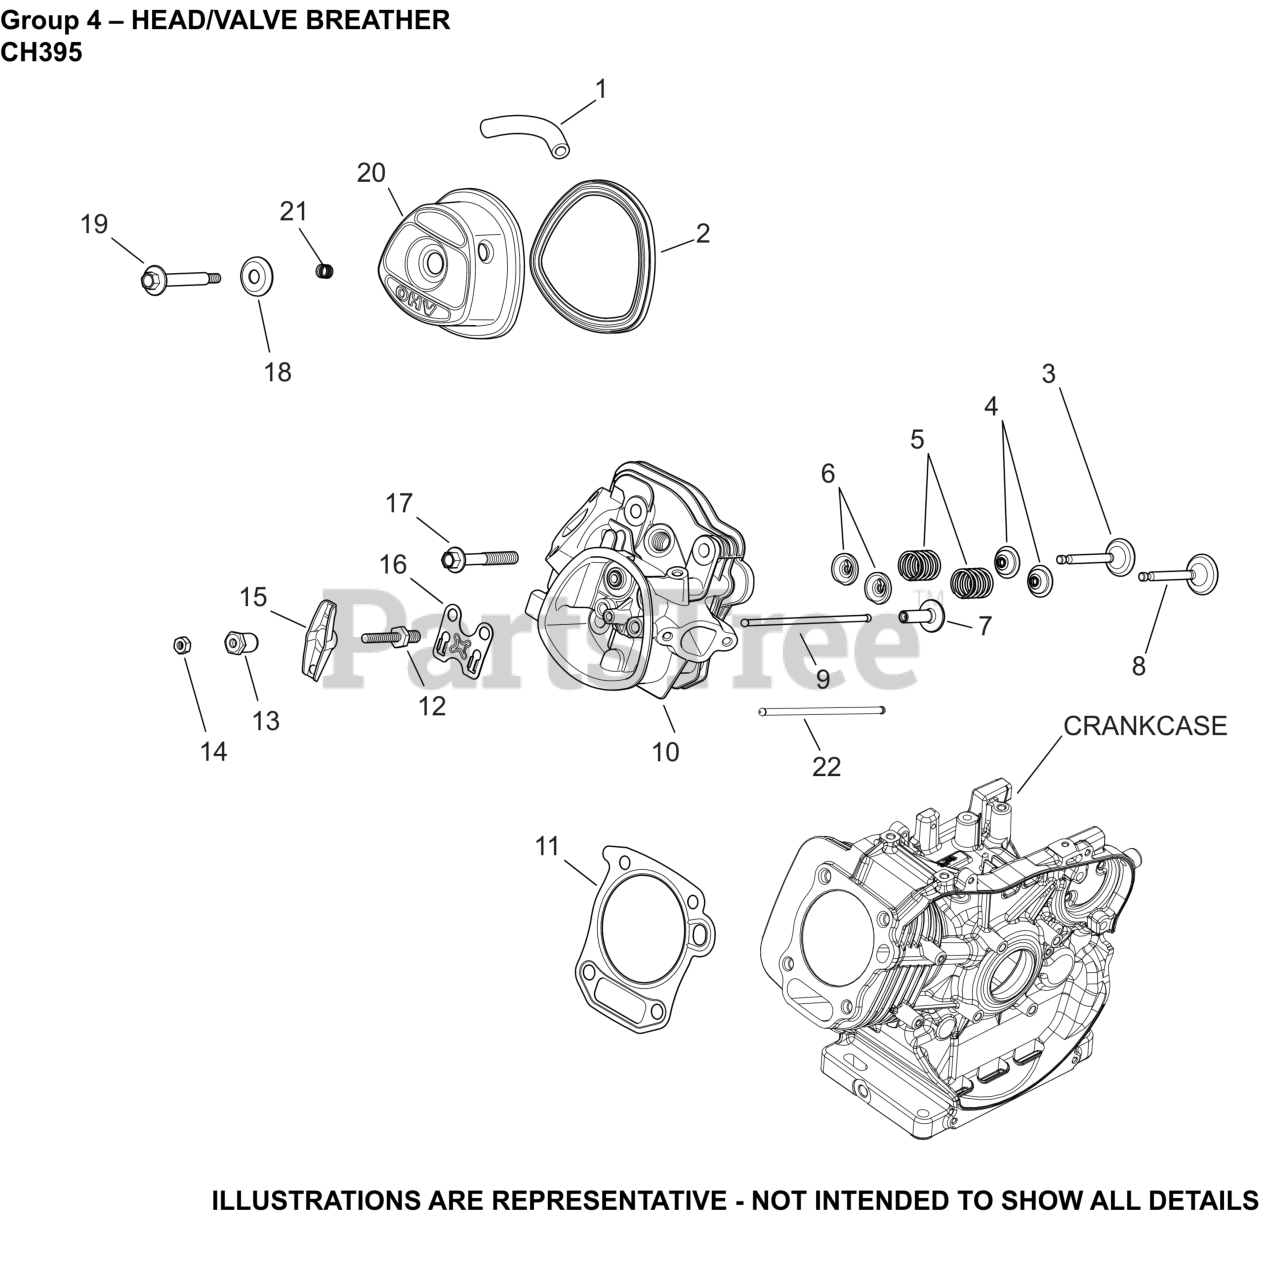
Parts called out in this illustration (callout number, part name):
1	TUBE, BREATHER
2	GASKET, VALVE COVER
3	VALVE, EXHAUST
4	SEAL, VALVE STEM
5	SPRING, VALVE
6	RETAINER, VALVE SPRING
7	LIFTER, VALVE
8	VALVE, INTAKE
10	KIT, HEAD AND VALVE TRAIN
11	KIT, HEAD GASKET
12	STUD, ROCKER ARM-USE 14 072 22-S
13	PIVOT, ROCKER ARM
14	NUT, HEX JAM
15	ARM, ROCKER
16	PLATE, PUSHROD GUIDE
17	SCREW, HEX FLANGE CYLINDER HEAD
19	SCREW, VALVE COVER SEAL ASSY
20	KIT, VALVE COVER ASSEMBLY
22	ROD, PUSH
